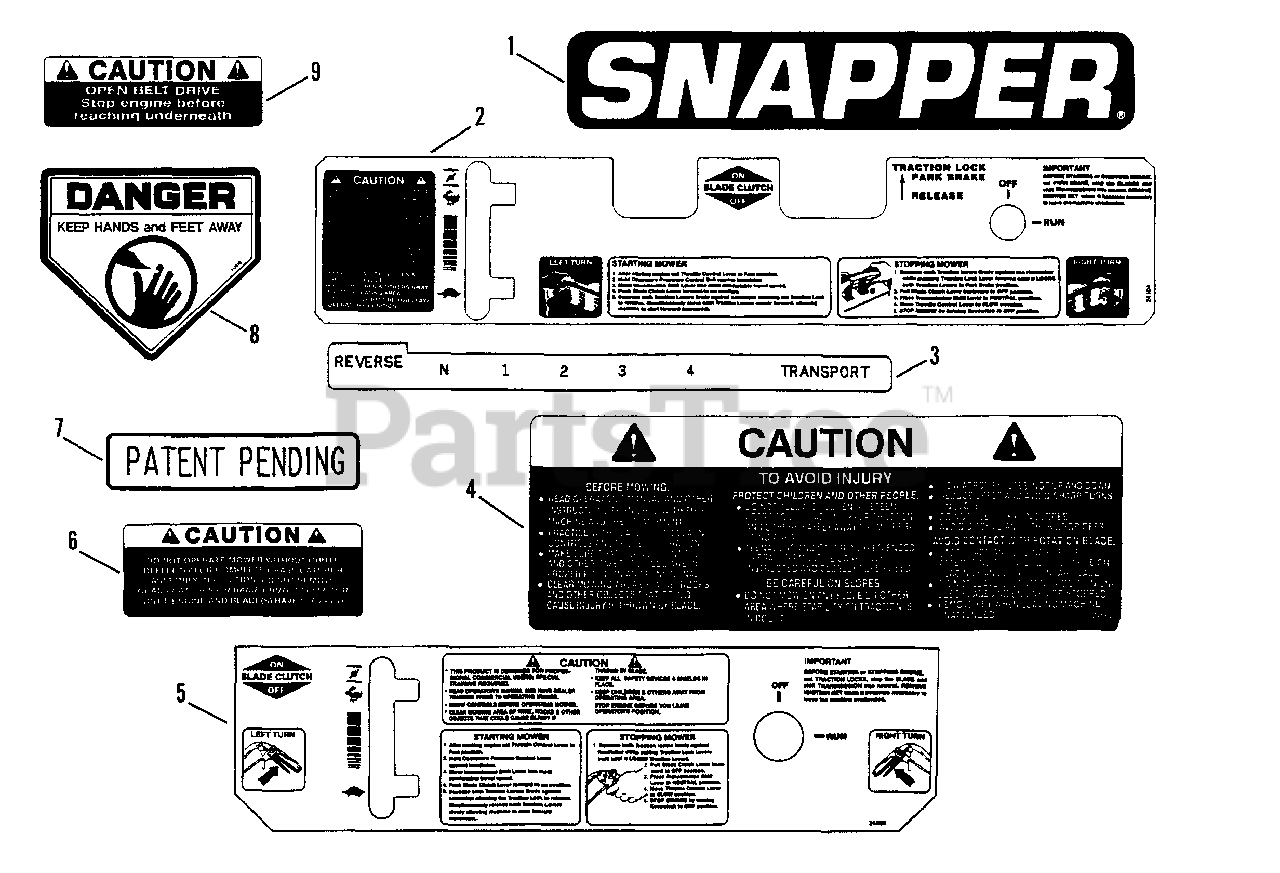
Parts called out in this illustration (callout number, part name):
1	DECAL, SNAPPER
2	DECAL, Console (Loop Handle)
3	DECAL, Shift Quadrant
4	DECAL, CAUTION
5	DECAL, Console (Pistol Grip Handle)
6	DECAL, CAUTION
7	DECAL, Patent Pending
8	DECAL, WARNING
9	DECAL, CAUTION
